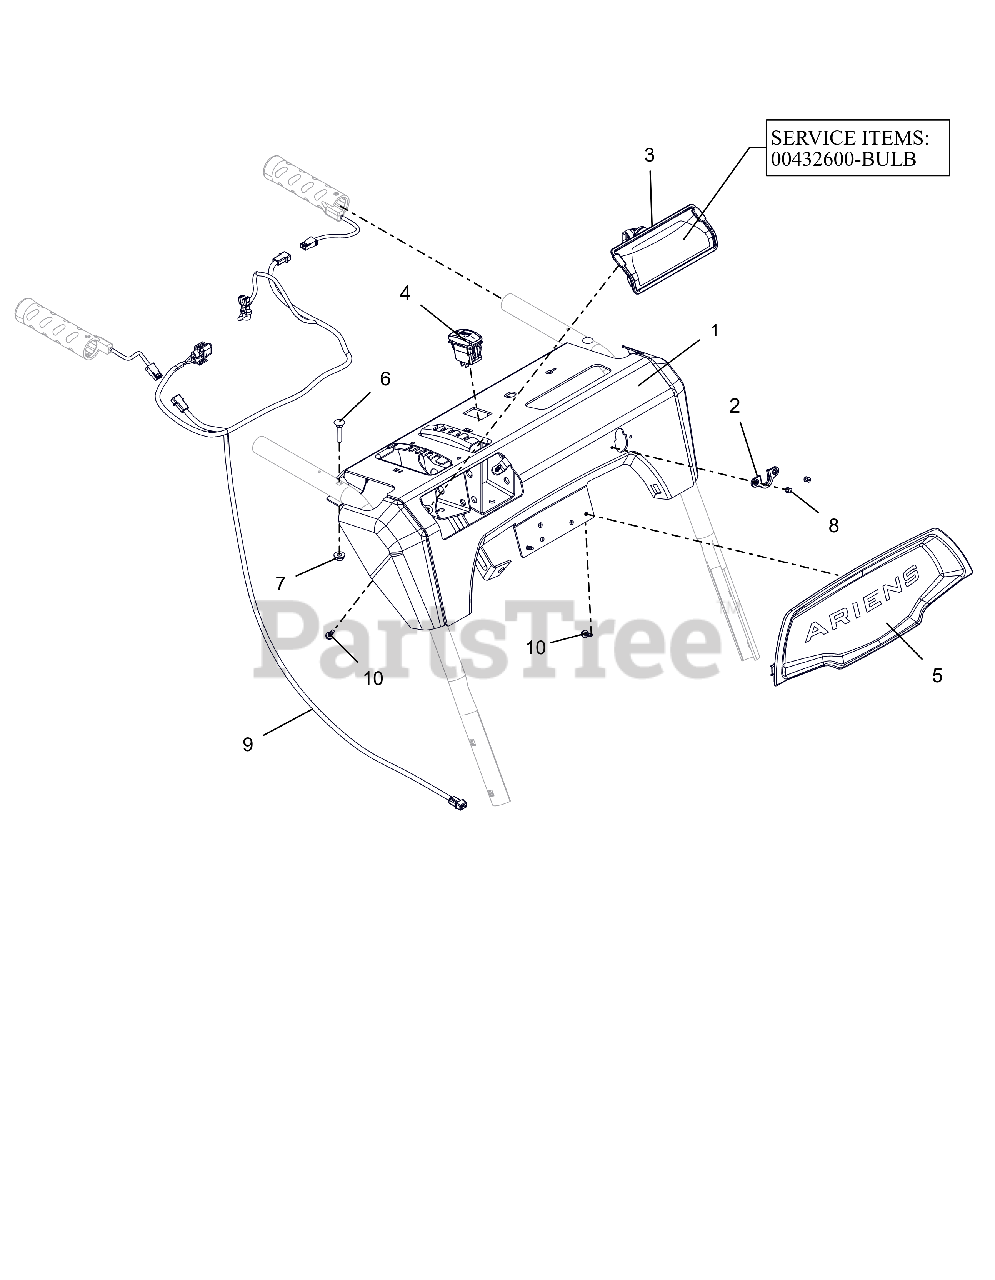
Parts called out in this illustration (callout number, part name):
1	CONTROL PANEL W/DECAL FRIC-QT
2	GROMMET, CABLE, QUICK TURN 2
3	HEADLIGHT ASY, HALO 20W 2SHOT
3	BULB, LIGHT-HALOGEN 20W
4	SWITCH,ROCKER SPST-ON/OFF
5	BEZEL, DASH - ARIENS LG DASH
6	BLT-RDHDXLSQNK.25-20X1.25 G5ZC
7	NUT-LK-CTR-FLG .25-20 ZC120
8	RVT-POP #43 .125X.313 STL ZINC
9	HARNESS, LIGHT & WARMER
10	SCR-TAP #10X.50 BOSS INDHXHD
